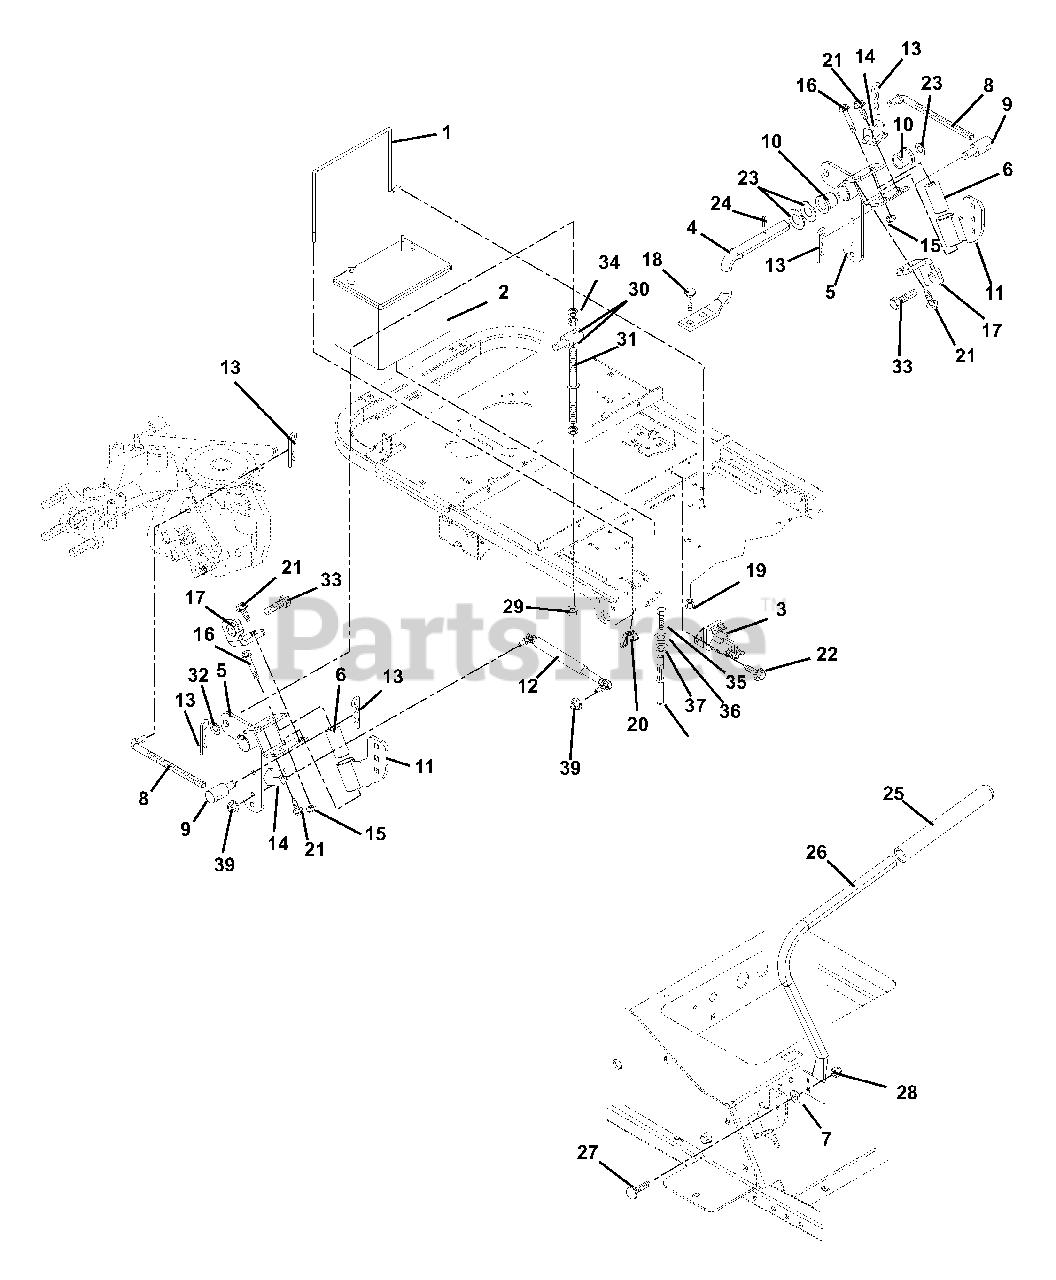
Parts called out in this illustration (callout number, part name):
1	BATTERY ROD
2	BATTERY, 300 CCA 10U1L
2	BATTERY W/ TUBE
3	SOLENOID
4	ROD PIVOT
5	WMT, CONTROL
6	BSHG, SPCR .502X.997X2.03 PM
7	@WSHR-LK-EXT.326X.599X.031YWZC
8	LINK,WIREFORM
9	PIVOT, ROD (TRUNNION ) .50
10	BUSHING-1"X.75"X1"
11	WELDMENT, HANDLEBAR RH
11	WELDMENT, HANDLEBAR LH
13	PIN-HAIR, ENDRIES #25 YWZC
14	SWITCH- DOUBLE POLE N.O./N.O.
15	@NUT-LK-TOP-FLG .50-13 YWZC
16	@BLT-HEX .50-13X3.00 GR5 YWZC
17	WMT, HANDLE STOP
18	@BLT-RDHDSQNK .38-16X1.00 G5YZ
19	@NUT-LK-NYL-FLG .38-16 YWZC
20	NUT-LK WING .250-20 YWZC
21	@SCR-TAP 10-24X.50 HWH TR YWZC
22	@SCR-TAP .25-20X.37 HWH YWZ TR
23	WSHR-FL-STL .754X1.000X.032 YZ
24	PIN-ROLL .188X1.13
26	HANDLEBAR WLDM'T RH
26	HANDLEBAR WLDM'T LH
27	BLT-RDHDSQNK.31-18X.88 GR5YWZC
28	@NUT-LK-NYL-FLG .31-18 YWZC
29	@NUT-LK-NYL-FLG .38-16 YWZC
30	@NUT-HEX .38-16 YWZC
31	TRACKING ROD
32	NUT-LK-JAM-PTCH 1.00-20
33	SCR-SKH .25-20X1.25 PL
34	TRUNNION
35	@BLT-HEX .31-18X1.00 GR5 YWZC
36	@WSHR-LK .31X.078 REG YWZC
37	@WSHR-FL-STL.344X.688X.065YWZC
39	NUT, TOP LOCK FLG 8X1.25 YWZC
